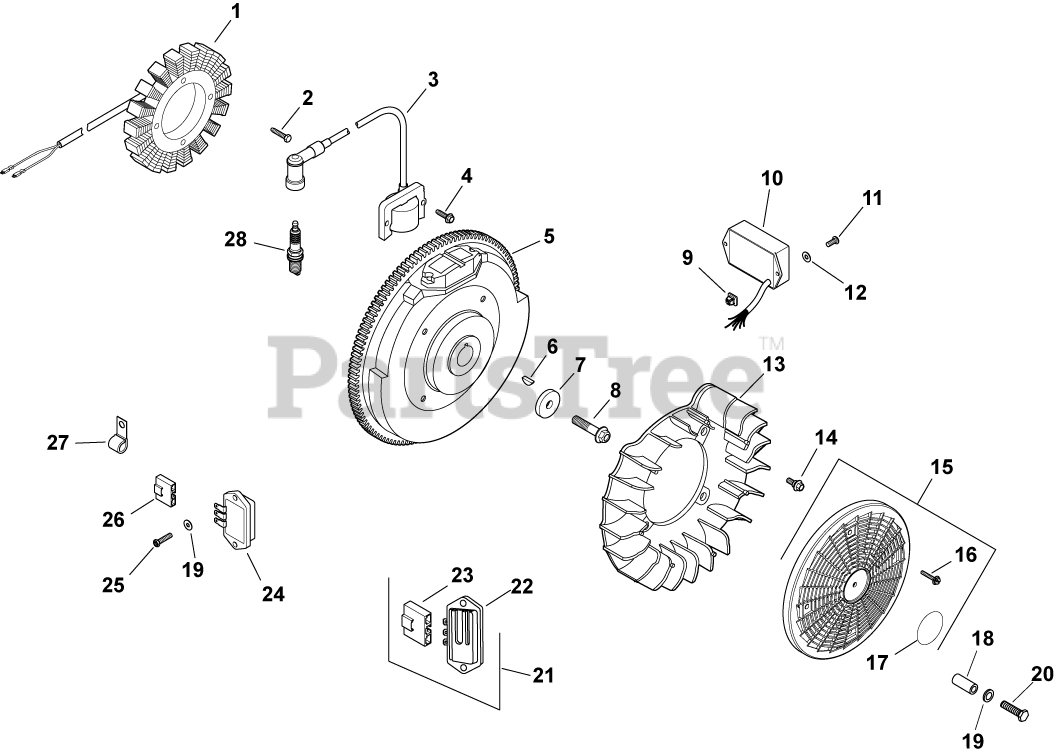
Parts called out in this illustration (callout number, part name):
1	KIT, 25 AMP STATOR ASSY.
2	SCREW, THD FROM M5X0.8X30
3	MODULE, IGNITION
4	SCREW, SKT THD FRM M5X0.8X25
5	FLYWHEEL, PAINTED-USE 24 025 57-S
6	KEY, 3/16" X 5/8"
7	WASHER, FLAT 13/32"
8	SCREW, FLG M10X1.5X45 - (#25086361S)
9	NUT, PLASTIC
10	MODULE, SPEED ADVANCE-DISCONTINUED SEE PB265
11	SCREW, PHL HD #11-16X1/2"
12	WASHER, FLAT 1/4" (O.D. 1/2")
13	FAN USE 24 157 11-S
14	BOLT, SHOULDER
15	KIT, GRASS SCREEN
16	SCREW, FLG SEMS M4X.7X25
17	DECAL, GRASS SCREEN USE 24 113 499-S
18	SPACER - DISCONTINUED
19	WASHER, FLAT 3/16"
20	SCREW, SLT HD CAP M4X0.7X25
21	KIT, FULL WAVE CONVERSION
22	REG/RECTIFIER (20/25 AMP)-USE 25 403 20-
23	CONNECTOR, BODY (KM)-USE 25 155 41-S
24	REG/RECT-15 AMP (KM)-USE 41 403 10-S
25	SCREW, PHL HD #11-16X7/8"
26	CONNECTOR, BODY (KM)-USE 25 155 41-S
27	CLIP, CABLE
28	PLUG, SPARK (STD)
